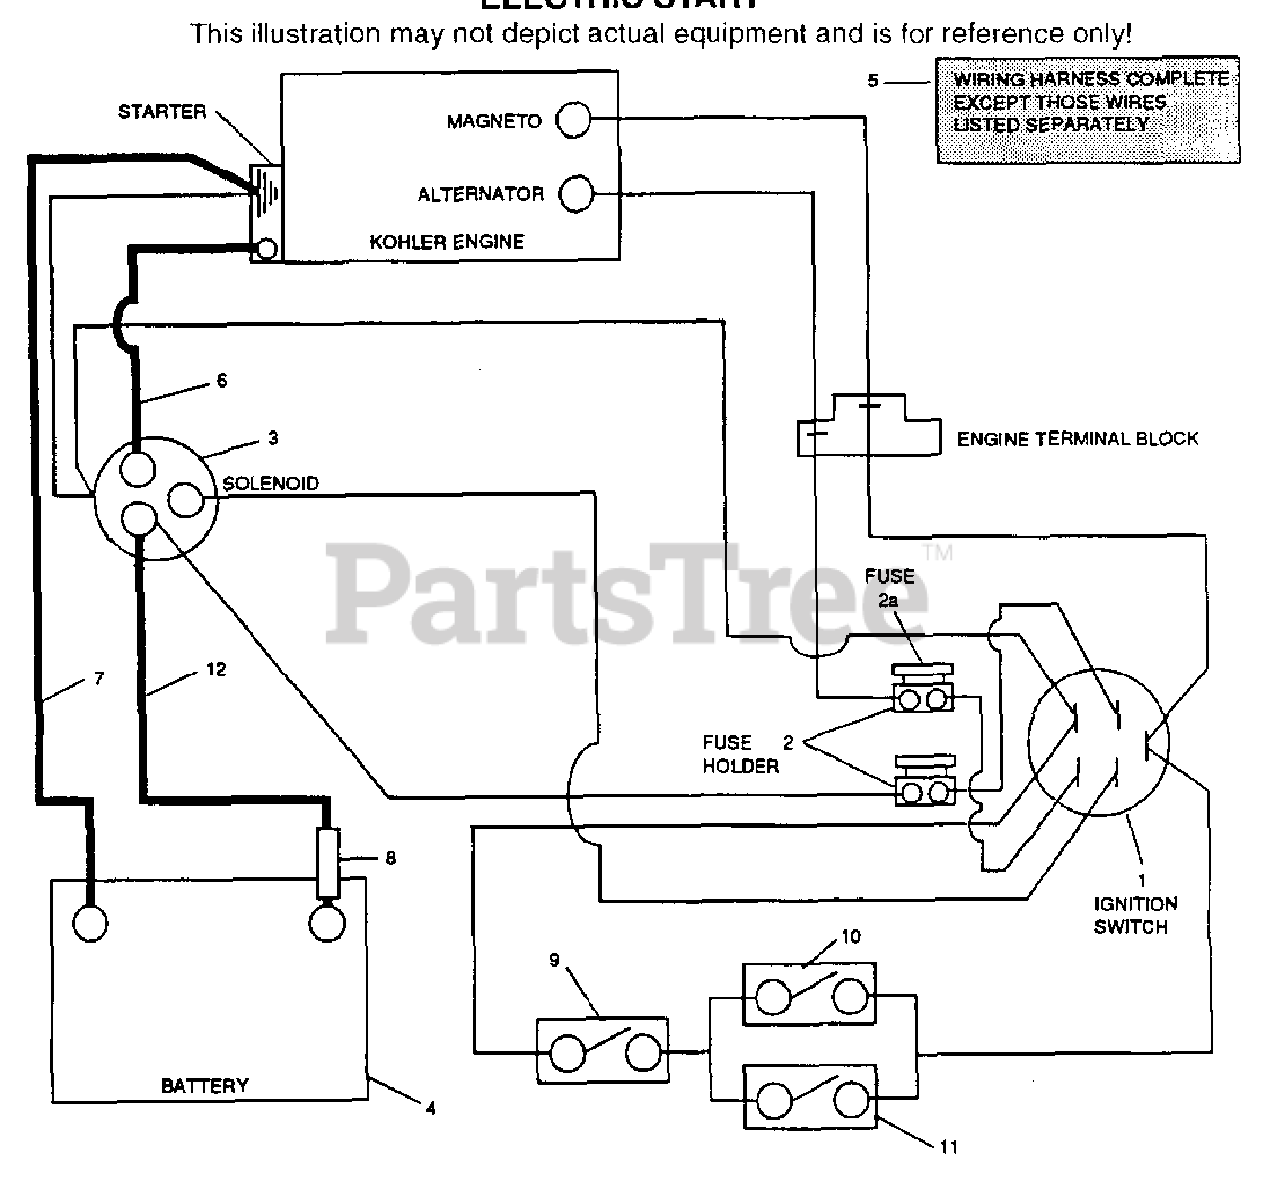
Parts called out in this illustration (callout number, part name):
1	KEY SWITCH
2	FUSE HOLDER
2A	FUSE 20 AMPS
3	SOLENOID
4	BATTERY MAY BE PURCHASED LOCALLY(U9-LM)
5	WIRING HARNESS COMPLETE
6	BATTERY CABLE - 13-3/4" RED
7	BATTERY CABLE - 20" BLACK
8	RUBBER BOOT
9	SWITCH, HANDLE INTERLOCK N.C.
10	SWITCH, CUTTER DRIVE INTERLOCK N.C.
11	SWITCH, NEUTRAL INTERLOCK N.C.
12	BATTERY CABLE - 31.5" RED
